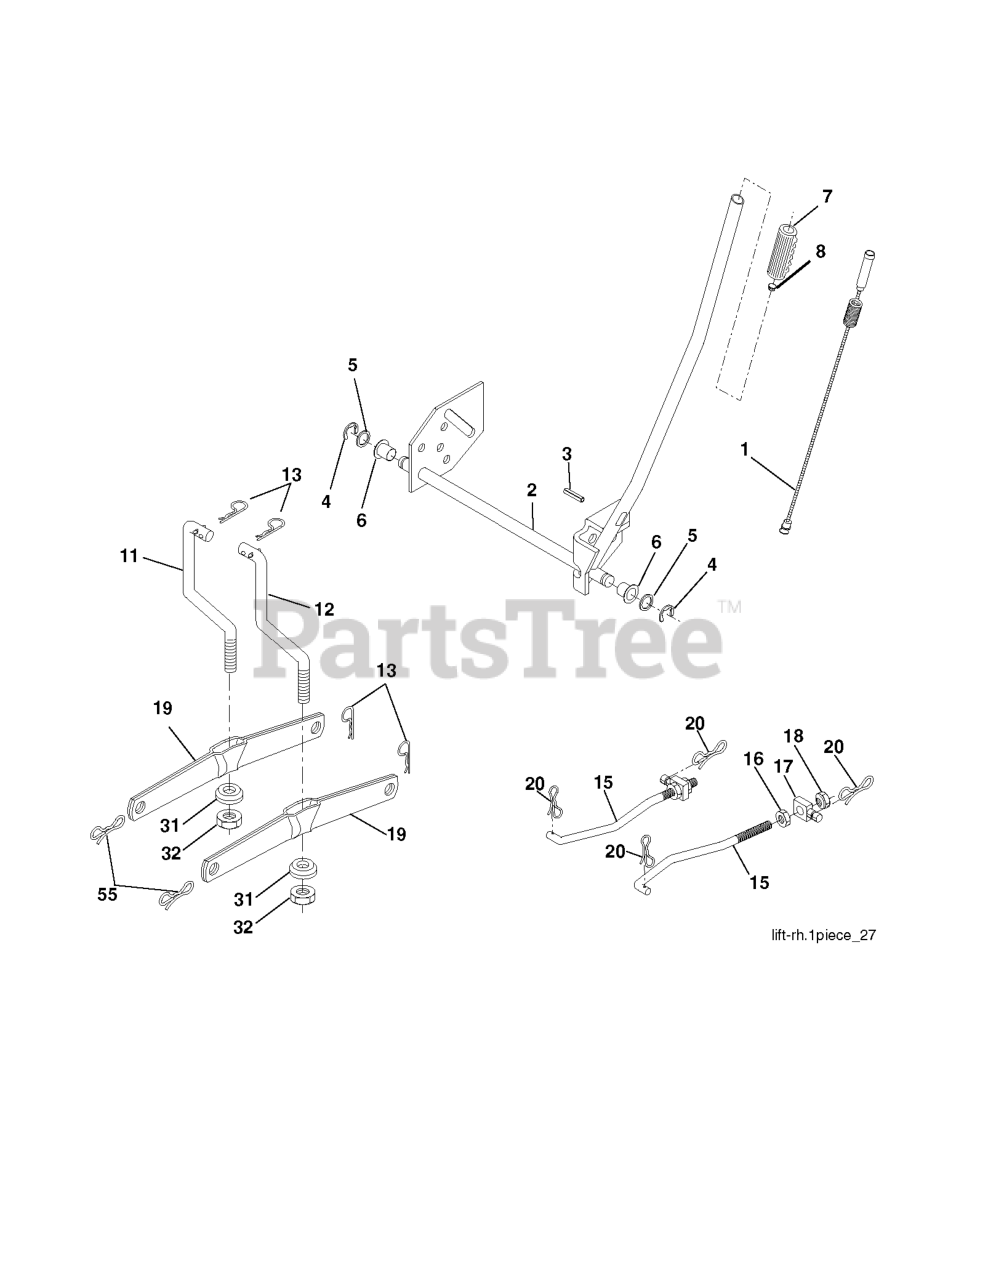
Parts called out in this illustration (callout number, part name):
1	WIRE ASM INNER W/ PLUNGER LT
2	SHAFT ASM R HANDLE
3	PIN GROOVE.
4	RETAINING RING LT
6	BEARING.NYLON
8	PLUNGER BUT KIT
11	LINK LIFT LH
12	LINK LIFT RH
13	RETAINER-SPRNG RB
15	LINK.SUSPENSION.FRONT
16	NUT.HEX.JAM.1/2-13
18	NUT.LK.W/WSH.1/2.
19	ARM.REAR.SUSPENSION
20	PIN.COTTER.7/16.BOW TI.
31	BEARING.PIVOT.LIFT
32	NUT CROWNLOCK 3/8-24
55	PIN.COTTER.5/16.BOW TI
